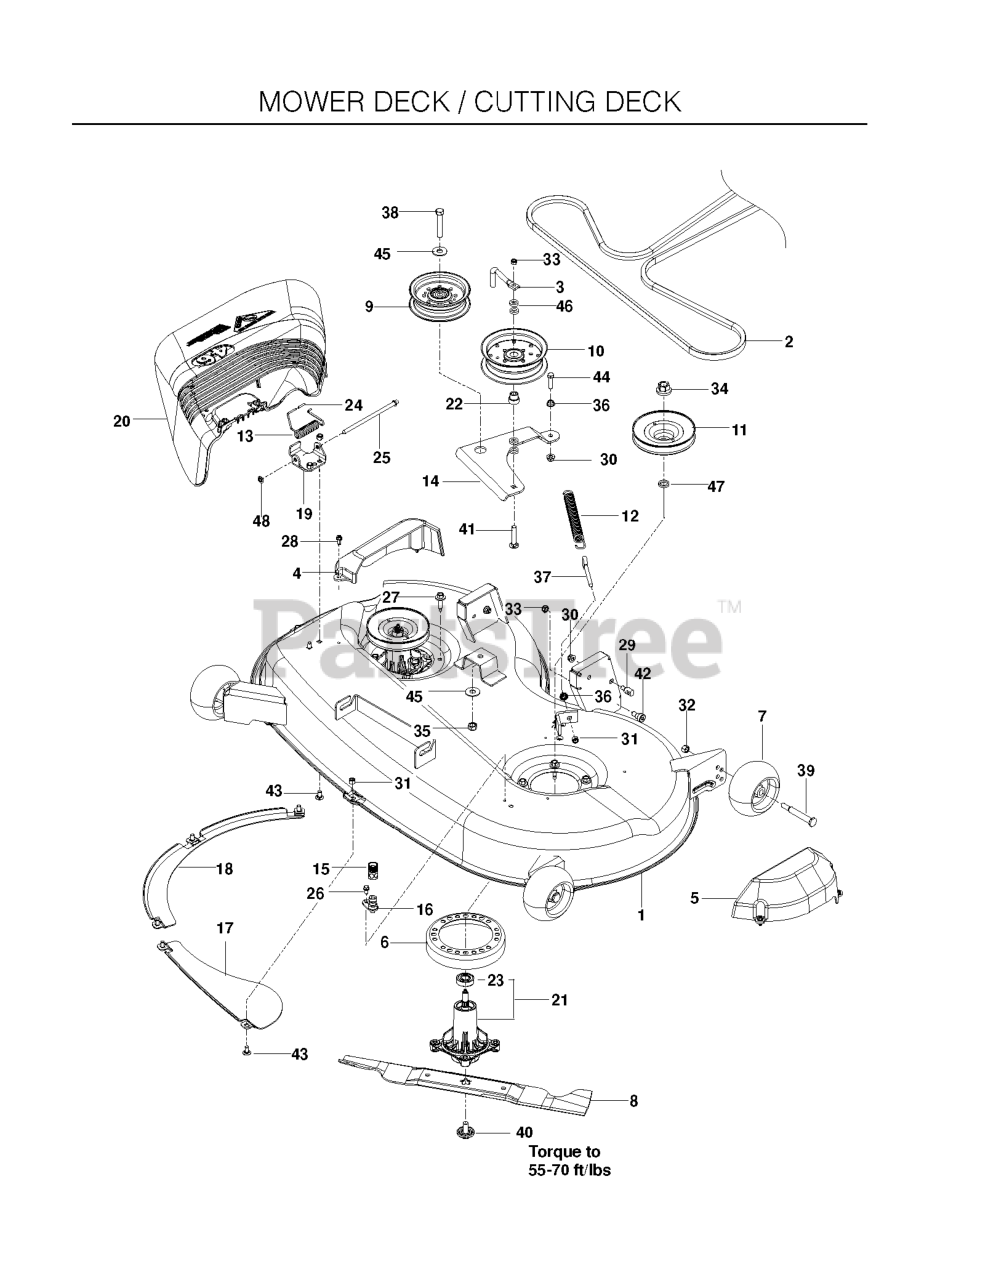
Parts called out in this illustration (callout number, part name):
1	DECK W/DECALS - RZ46
3	BELT KEEPER 5"
4	COVER.MANDREL.RH.46"
5	COVER.MANDREL.LH.46"
6	STRIPPER-ROUND-UNIVERSAL
7	GAUGE WHEEL
8	BLADE.MOWER.46".HI.LIFT
9	PULLEY.IDLER.MWR.STATI.LH
10	PULLEY, IDLER
11	RP.PULLEY, DECK
12	SPRING, DECK BELT
13	TORSION SPRING
14	ARM, IDLER BLK
15	COUPLING.QUICK CONNECT
16	PORT.WASHOUT
17	BAFFLE CENTER FRONT
18	BAFFLE FRONT RH
19	BRKT.DEFLECTOR.38"2005+
20	SHIELD.DEFLECTOR.MOWER.46"BLAC
21	CUTTER HOUSING
22	IDLER BUSHING
24	CAP-SLEEVE
25	ROD, HINGE
26	SCREW #10 X 1/2 SELF TAPPING
27	WASHER HEAD SCREW
28	SCREW- 1/4-20 X 5/8
29	STUD.FASTNER.W/ANTI-ROTATE
30	5/16-18 NYLOC FLANGE NUT
31	NUT 5/16 NYLOC
32	NUT 3/8-16 NYLOC
33	NUT HEX 3/8-16 NYLON, THIN
34	LOCKNUT - 9/16
35	7/16-14 HEX NUT W/NYL RING ZD
36	NUT 5/16C WHIZ
37	EYE BOLT 5/16 X 3.50
38	BOLT 7/16-14 X 2-1/2 GR 5 ZD
39	SHOULDER BOLT 1/2X2-5/8 ZD SPE
40	BOLT.WASHER.ASM.7/16-2
41	CARRIAGE BOLT 3/8-16 X
42	SB 3/8-16 X 3/8 SKT HD ZD
43	BOLT 5/16C X 3/4" CARRIAGE
44	HCS 5/16C X 1 1/4
45	WASHER 7/16 FLAT ZD
46	WASHER 3/8 X 3/4 X .187 TK
47	WASHER-SPACER
48	PUSH NUT
